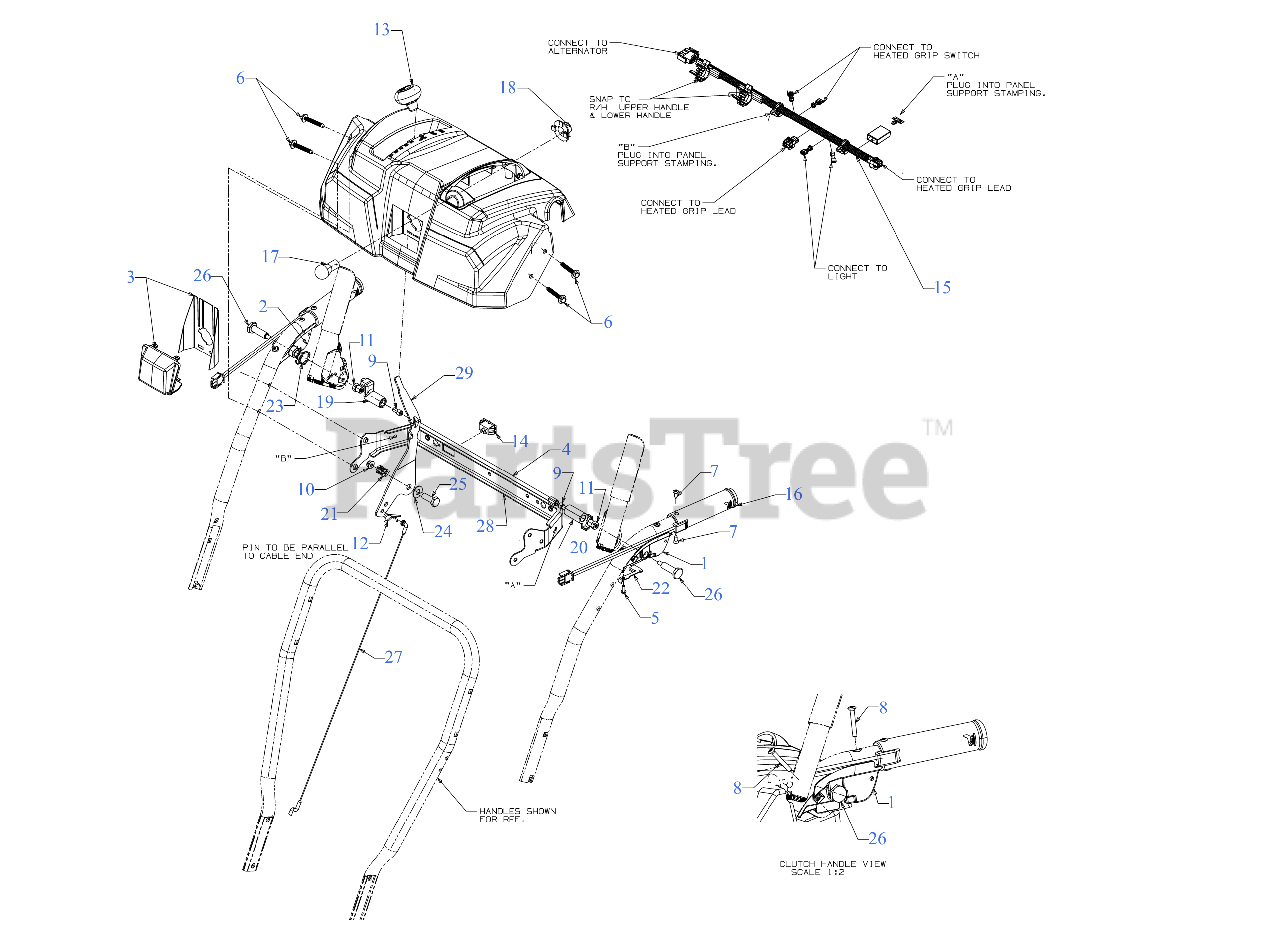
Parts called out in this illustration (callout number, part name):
1	CLUTCH LOCK HANDLE ASSEMBLY (LH)
2	CLUTCH LOCK HANDLE ASSEMBLY (RH)
3	HANDLE PANEL ASSEMBLY
5	SCREW #8-16 x .50
6	SCREW 1/4-20 x 1.625
7	SCREW-AB #12-24 x .625
8	SCREW #10-24 x 1.375
9	SCREW 1/4-20 x .50
10	FLANGE LOCK NUT
11	HEX NUT W/PATCH
12	INTERNAL COTTER PIN
13	SHIFT KNOB
14	HEATED GRIP SWITCH
15	HEATED GRIPS HARNESS
16	HEATED GRIP
17	LAMP-12 VOLT
18	HEADLIGHT SOCKET
20	CLUTCH LOCK CAM
21	COMPRESSION SPRING
22	CLUTCH SPRING
23	TORSION SPRING
24	FLAT WASHER .40X.88X.060
25	SHOULDER SCREW
26	SHOULDER SCREW .437 x 1.345 1/4-20
27	SPEED SELECTOR CABLE (PLASTIC)
28	HANDLE SUPPORT BRACKET (POWDER BLACK)
